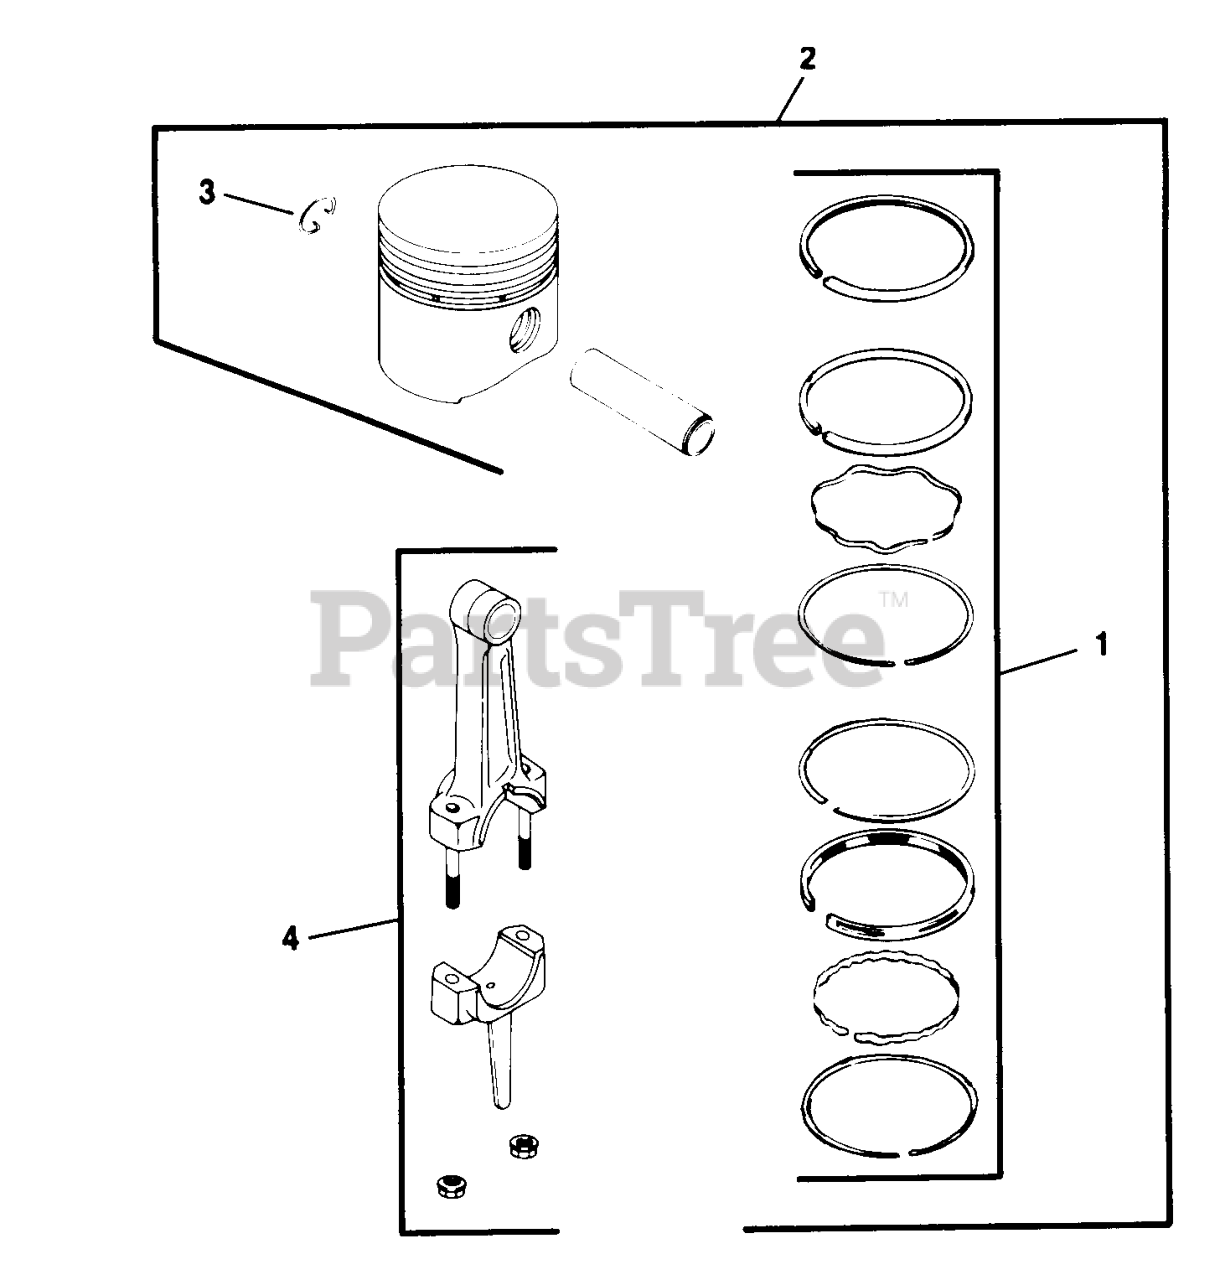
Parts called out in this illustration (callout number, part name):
1	RINGS STD. - DISCONTINUED
1	RINGS .010
1	RINGS .020
1	RINGS .030
2	KIT, PISTON W/RING SET STD
2	PISTON W/RING SET .003
2	KIT, PISTON W/RING SET .010-(#DSC)
2	KIT, PISTON W/RING SET .020
2	PISTON W/RING SET .030
4	ROD STD. - DISCONTINUED
4	ROD .010 (KM) - DISCONTINUED
